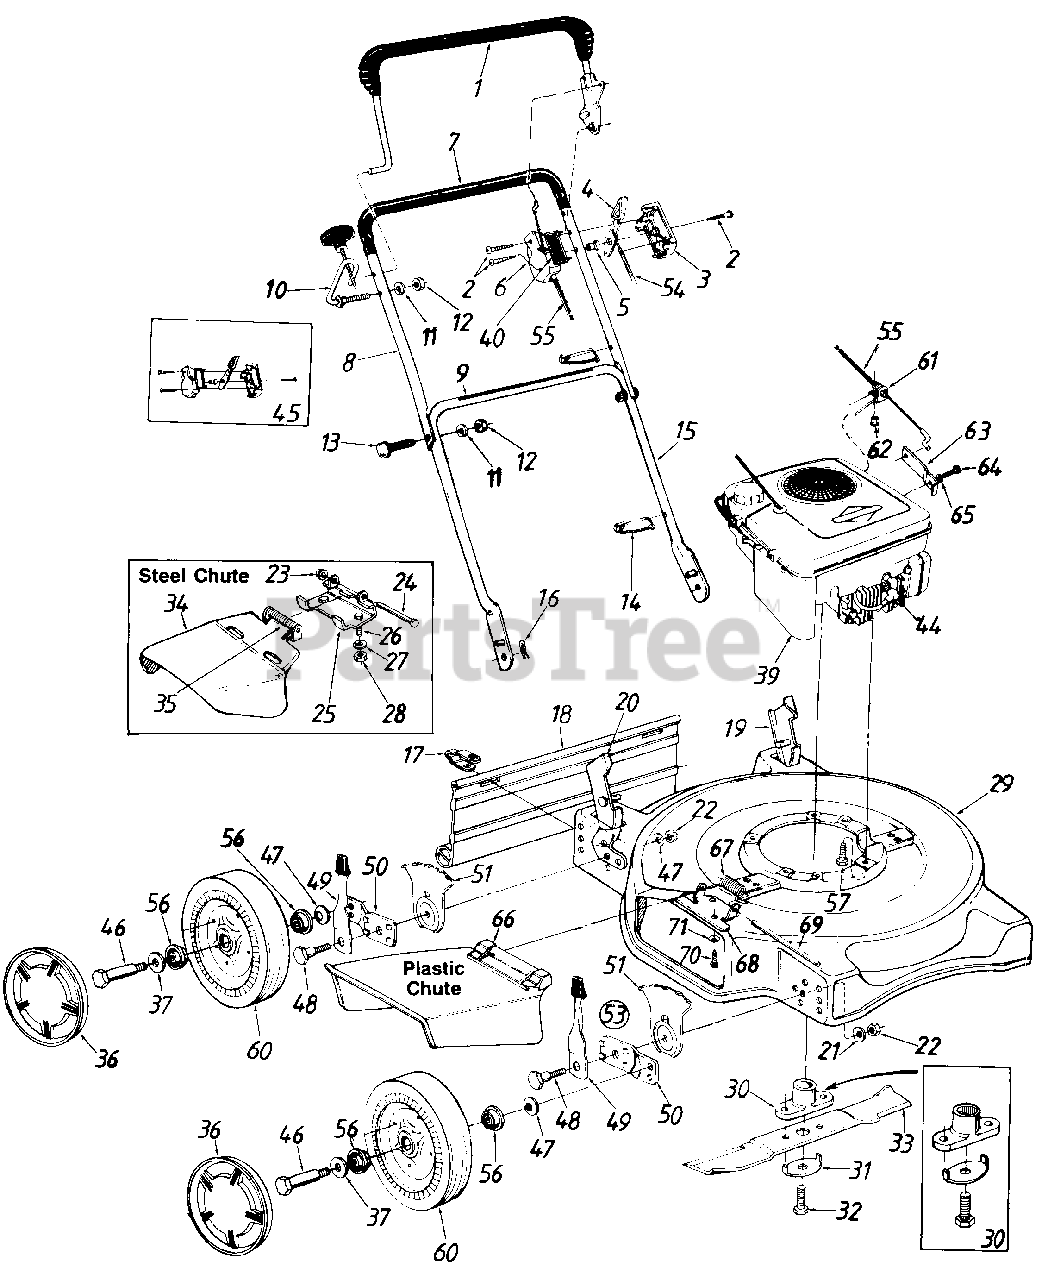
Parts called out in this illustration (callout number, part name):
1	Control Handle Ass'y.
2	Truss Mach. Scr. #12 x 1.5" Lg.
3	Control Panel Half
4	Throttle Control Lever
5	Control Disc Pin
6	Clutch Panel Half
8	Upper Handle
9	Instruction Label-Handle
10	Rope Guide Bolt
11	L-Wash. 5/16" I.D.*
12	Hex Nut 5/16-18 Thd.*
13	Curved Carriage Bolt 5/16-18 x 1.38" Lg.
14	Cable Tie
16	Hairpin Cotter
17	Hinge Clip
18	Rear Flap
19	Handle Bracket Ass'y.-L.H.
20	Handle Bracket Ass'y.-R.H.
21	Bell-Wash. .39" I.D. x 1.38"
22	Hex Nut 3/8-16 Thd.*
23	Push Cap 1/4" Rod
24	Pivot Pint
25	Adapter Plate
26	Hex Bolt 1/4-20 X .50" Lg.*
27	L-Wash. 1/4" I.D.*
28	Hex Nut 1/4-20 Thd.*
31	Blade Bell-Wash. .45" I.D. x 2.38"
32	Hex Bolt 7/16-20 x 1.5" Lg.
33	20" Blade
34	Chute Deflector Ass'y
35	Torsion Springt
36	Hub Cap
37	FL-Wash. .531" I.D.
39	Engine
40	Control Label-Throttle
44	Spark Plug Boot
45	Kit-Control Housing Comp.
46	Axle Bolt
47	Bell-Wash. .400" I.D. x .88"
48	Shld. Bolt .50" Dia. x .357"
49	Spring Lever Ass'y. w/Knob
51	Height Adj. Plate
53	Height Adj. Ass'y. Comp.-R.H.
53	Height Adj. Ass'y. Comp.-L.H.
54	Throttle Cable-47"
55	Control Cable-43"
56	Ball Bearing
57	Hex L-Wash. Hd. Scr. 3/8-16 x 1.0" Lg.
60	Wheel Ass'y. Comp.
61	Cable Mounting Bracket
62	Pop Rivet
63	Mounting Brkt.
64	Truss Mach. Scr. #10-24 x .5" Lg.
65	L-Wash. #10 I.D.
66	Chute Deflector Ass'y.
67	Torsion Spring
68	Adapter Plate
69	Hinge Pin
70	Hex Self-Tap Scr. 1/4-20 X .5" Lg.
71	Bell-Wash. 1/4" I.D.
